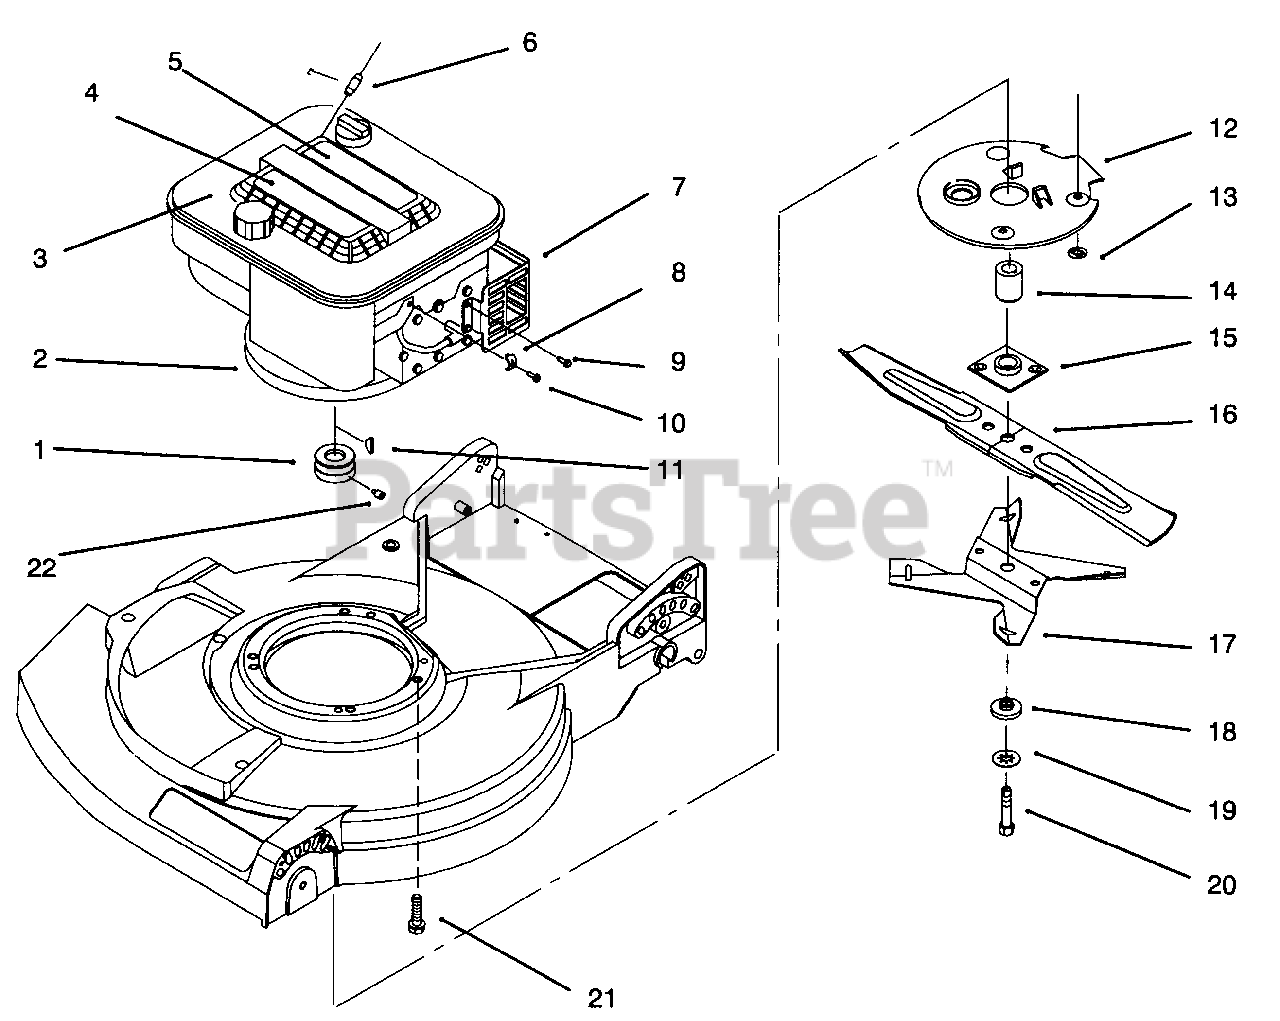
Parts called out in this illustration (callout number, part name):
1	Pulley-Engine (Self Propelled)
2	Engine-Briggs & Stratton
3	Grille-Engine
4	Decal-Recoil (Self Propelled)
5	Decal-Recoil
6	Stop-Rope
7	Shield-Muffler
8	Clamp-Cable
9	Screw-Hex. Hd.
11	Key-Woodruff
12	Shield-Grass (Self Propelled)
13	Nut-Push (Self Propelled)
14	Hub-Blade Driver
15	Plate-Blade Driver
16	Blade-21 "
17	Fan-Mulching
19	Washer-Lock
20	Bolt-Blade
21	Screw
22	Screw-Set (Self Propelled)
